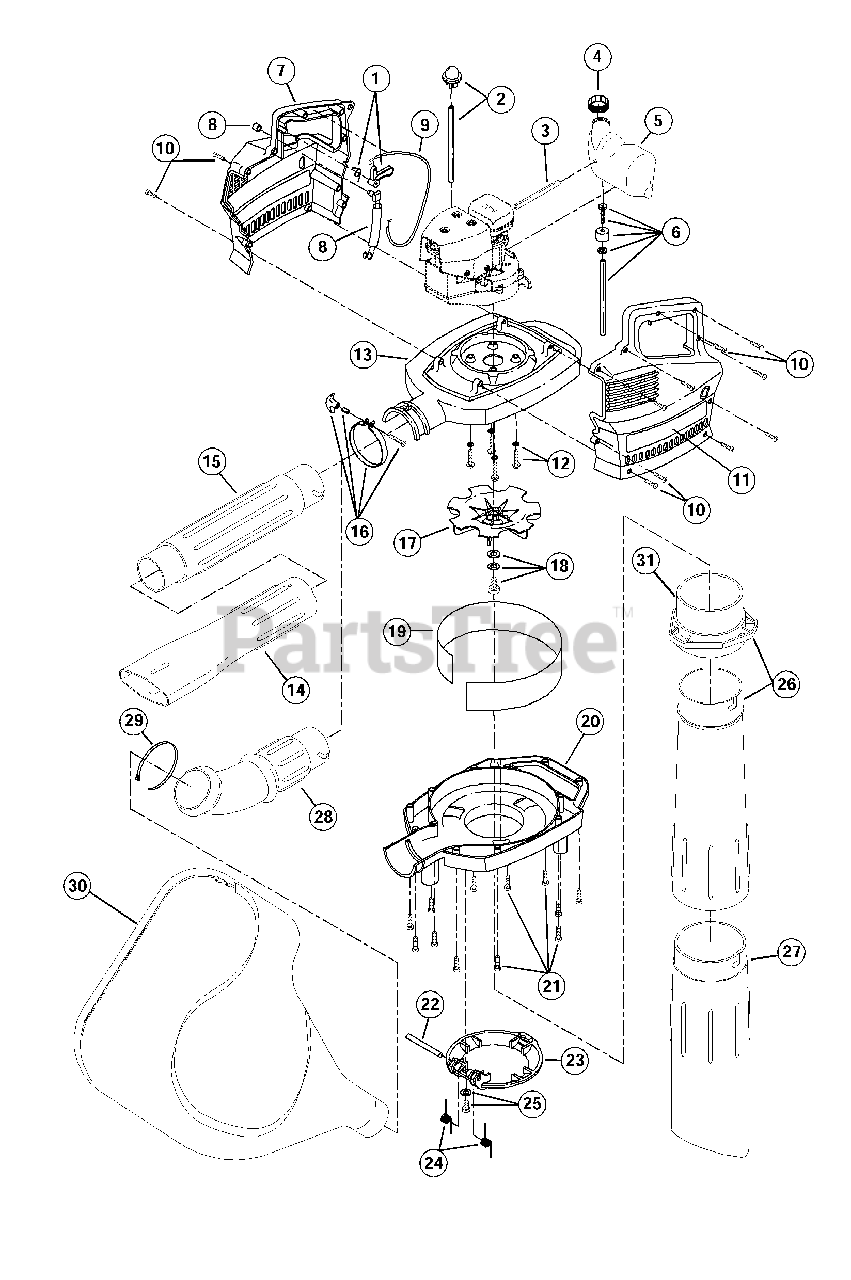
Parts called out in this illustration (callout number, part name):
1	Trigger Assembly
2	Primer Bulb and Hose Assembly
3	Return Line Assembly
4	Fuel Cap Assembly
5	Complete Fuel Tank Assembly
6	Fuel Line Assembly
7	R.H. Engine Cover
8	Switch and Lead Assembly
9	Throttle Wire and Housing Assembly
10	Mounting Screw Assembly
11	L.H. Engine Cover
12	Mounting Screw Assembly
13	Upper Blower Housing
14	Blower Tube/w Nozzle
15	Blower Tube
16	Clamp Assembly
17	Impeller
18	Mounting Bolt Assembly
19	Impact Shield
20	Lower Blower Housing
21	Mounting Bolt Assembly
22	Hinge Shaft
23	Intake Cover
24	Spring Set
25	Mounting Screw Assembly
26	Upper Vacuum Tube and Adapter
27	Lower Vacuum Tube
28	Elbow
29	Clamp
30	Vacuum Bag Assembly
31	Adapter-Upper Vacuum Tube
